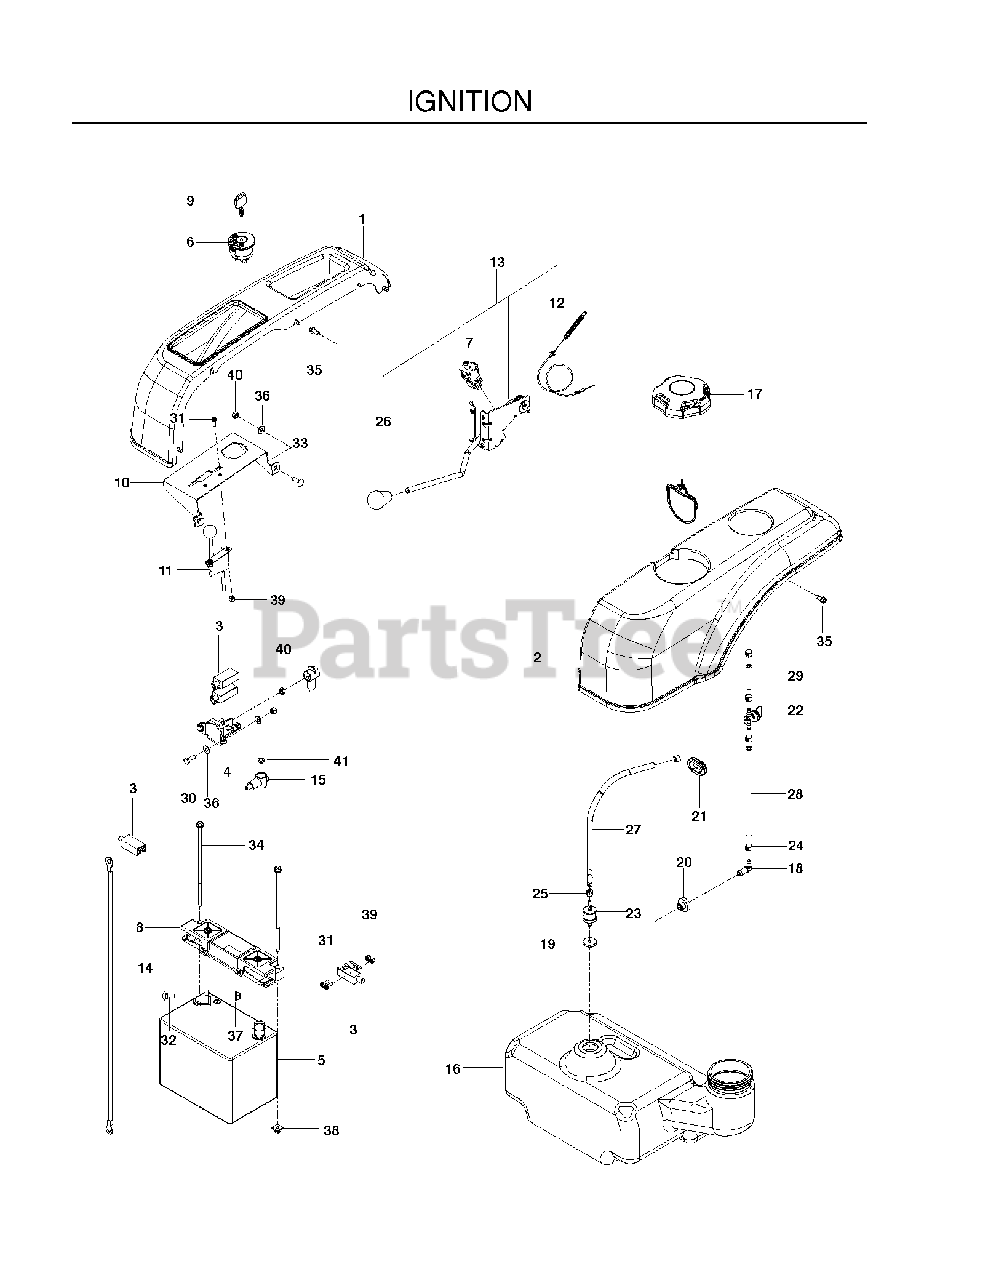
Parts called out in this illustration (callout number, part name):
1	FENDER, RZ 30/38 RT
2	FENDER, RZ 30/38 LT
3	SWITCH, INTERLOCK
5	BATTERY, 12 V 330 AMP
6	RP IGNITION SWITCH
7	SWITCH INTERLOOK PUSH-IN
8	BATTERY HOLD DOWN
9	KEY
10	MOUNT, CONTROLS, BLK
11	CABLE, THROTTLE
12	CABLE.CLUTCH.38".SERVICE
13	ASM, CLUTCH ENGAGE W/CABLE
14	BATTERY CABLE, NEGATIVE
15	TERMINAL COVER-SM
16	TANK, FUEL EPA
17	CAP, FUEL
18	STEM, FUEL TANK
19	GROMMET, CHECK VALVE
20	RUBBER GROMMET
21	RUBBER GROMMET
22	FUEL VALVE
23	VALVE.FUEL.CHECK
24	HOSE CLAMP
25	CLAMP, HOSE
26	KNOB - SHIFT
27	HOSE, FUEL, 3/16" X 20"
28	HOSE 1/4 X 8
29	HOSE 1/4 X 2"
30	HCS 1/4C X 3/4 HCS
31	SCREW #10-24 X 5/8
32	BOLT 5/16C X 3/4" CARRIAGE
33	RHSNB 1/4C X 3/4
34	Bolt, 1/4-20 X 7.5
35	SCREW 1/4 X 5/8
36	WASHER 1/4 SAE
37	5/16-18 NYLOC FLANGE NUT
38	PUSH NUT-NYLON
39	NUT 10-24 NYLOC
40	RP_NUT 1/4-20 NYLOC
41	JAM NUT 1/4C (2 2 PW01)
